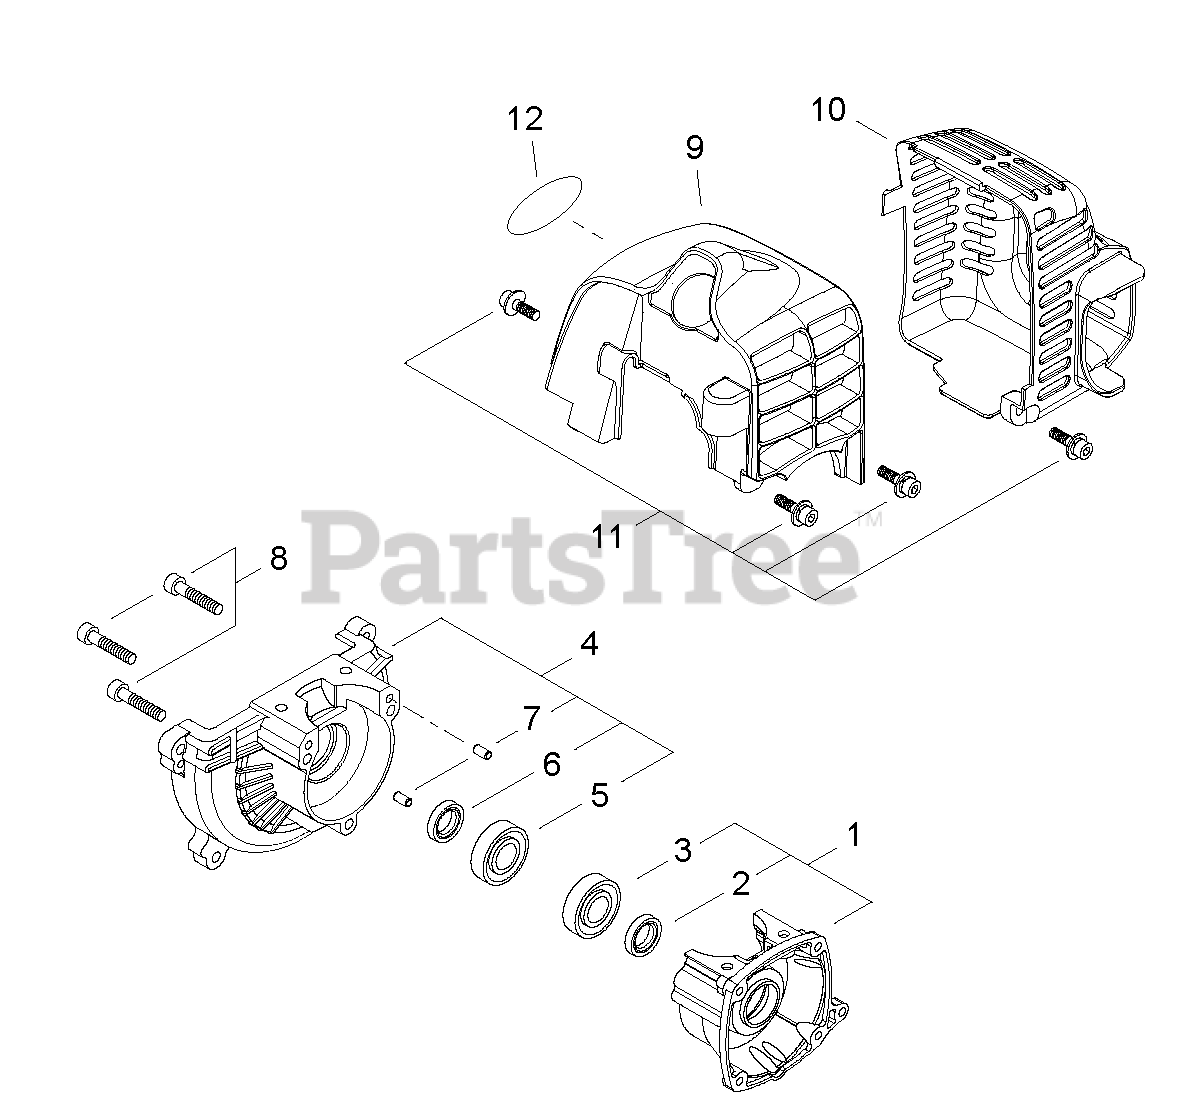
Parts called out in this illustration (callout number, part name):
1	CRANKCASE ASSY, S
2	SEAL, OIL 12
3	BEARING, BALL 6001 C3
4	CRANKCASE ASSY, M
5	BEARING, BALL 6001 C3
6	SEAL, OIL 12
7	PIN, LOCATING Ø4×8
8	BOLT 5×25
9	COVER, ENGINE
10	COVER, MUFFLER
11	BOLT M4×16
12	LABEL, HOME PRO ID
